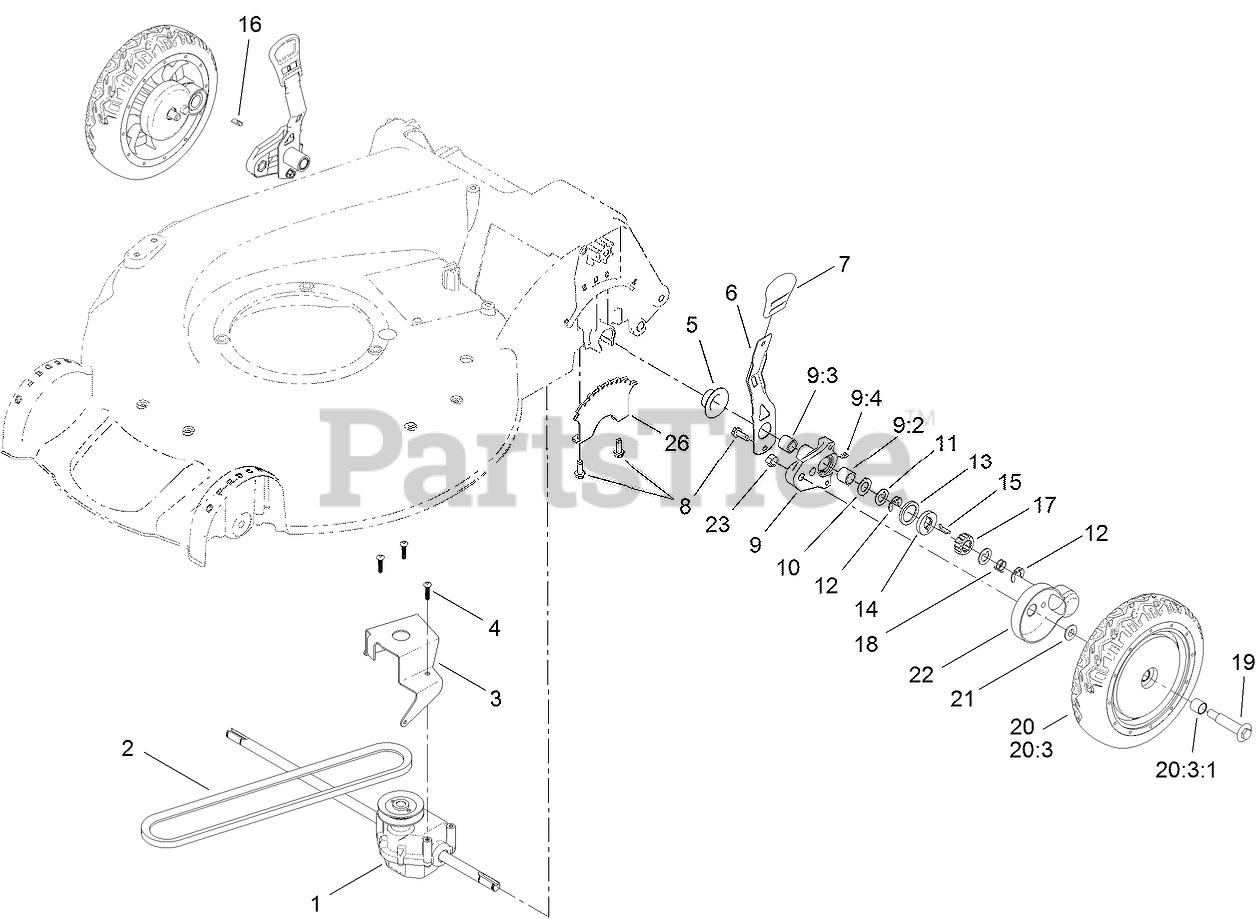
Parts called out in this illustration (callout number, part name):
1	TRANSMISSION ASM
2	V-BELT
3	BRACKET-TRANSMISSION
4	SCREW-PLASTITE
5	CAP-END
6	ARM-SPRING
7	KNOB-HOC
8	SCREW-HWHTF
9	PIVOT ARM ASM
9:2	BUSHING
9:3	BUSHING
9:4	FITTING-GREASE
10	WASHER-ARM, PIVOT
11	WASHER-THRUST, KEYED
12	RING-CLIP, LOCKING
13	RING-FRICTION
14	WASHER-CLUTCH
15	KEY-ROCKING, LH
16	KEY-ROCKING, RH
17	GEAR-PINION
18	SPRING-COMPRESSION
19	BOLT-SHOULDER
20	WHEEL GEAR ASM
20:3	WHEEL ASM
20:3:1	BUSHING
21	SPACER-COVER, WHEEL
22	COVER-WHEEL
26	PLATE-HOC
